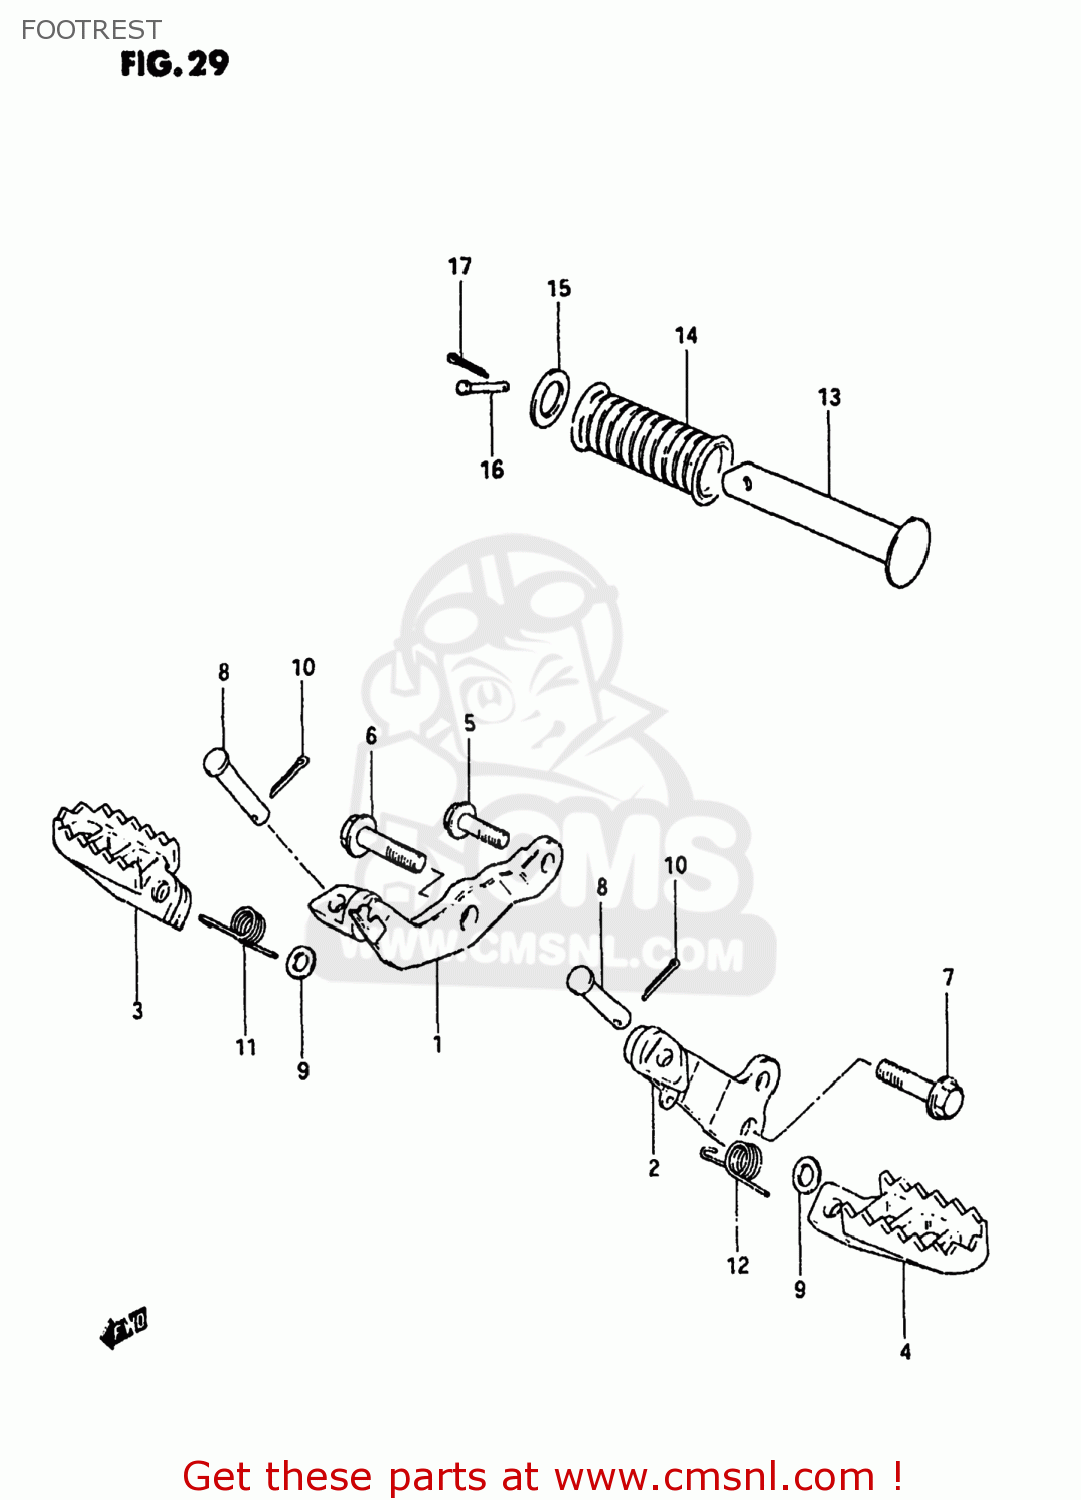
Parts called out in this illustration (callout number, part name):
1	BAR,FRONT FOOTREST
2	BAR,FRONT FOOTREST,LEFT
3	FOOTREST,RIGHT
4	FOOTREST
5	BOLT
6	BOLT, RH
7	BOLT
8	PIN
9	WASHER
10	PIN 20X20
11	SPRING
12	SPRING
13	BAR,FOOTREST RUBBER
14	RUBBER,PILLION FOOTREST
15	WASHER (19.5X32X2)
16	PIN
17	PIN 20X20
